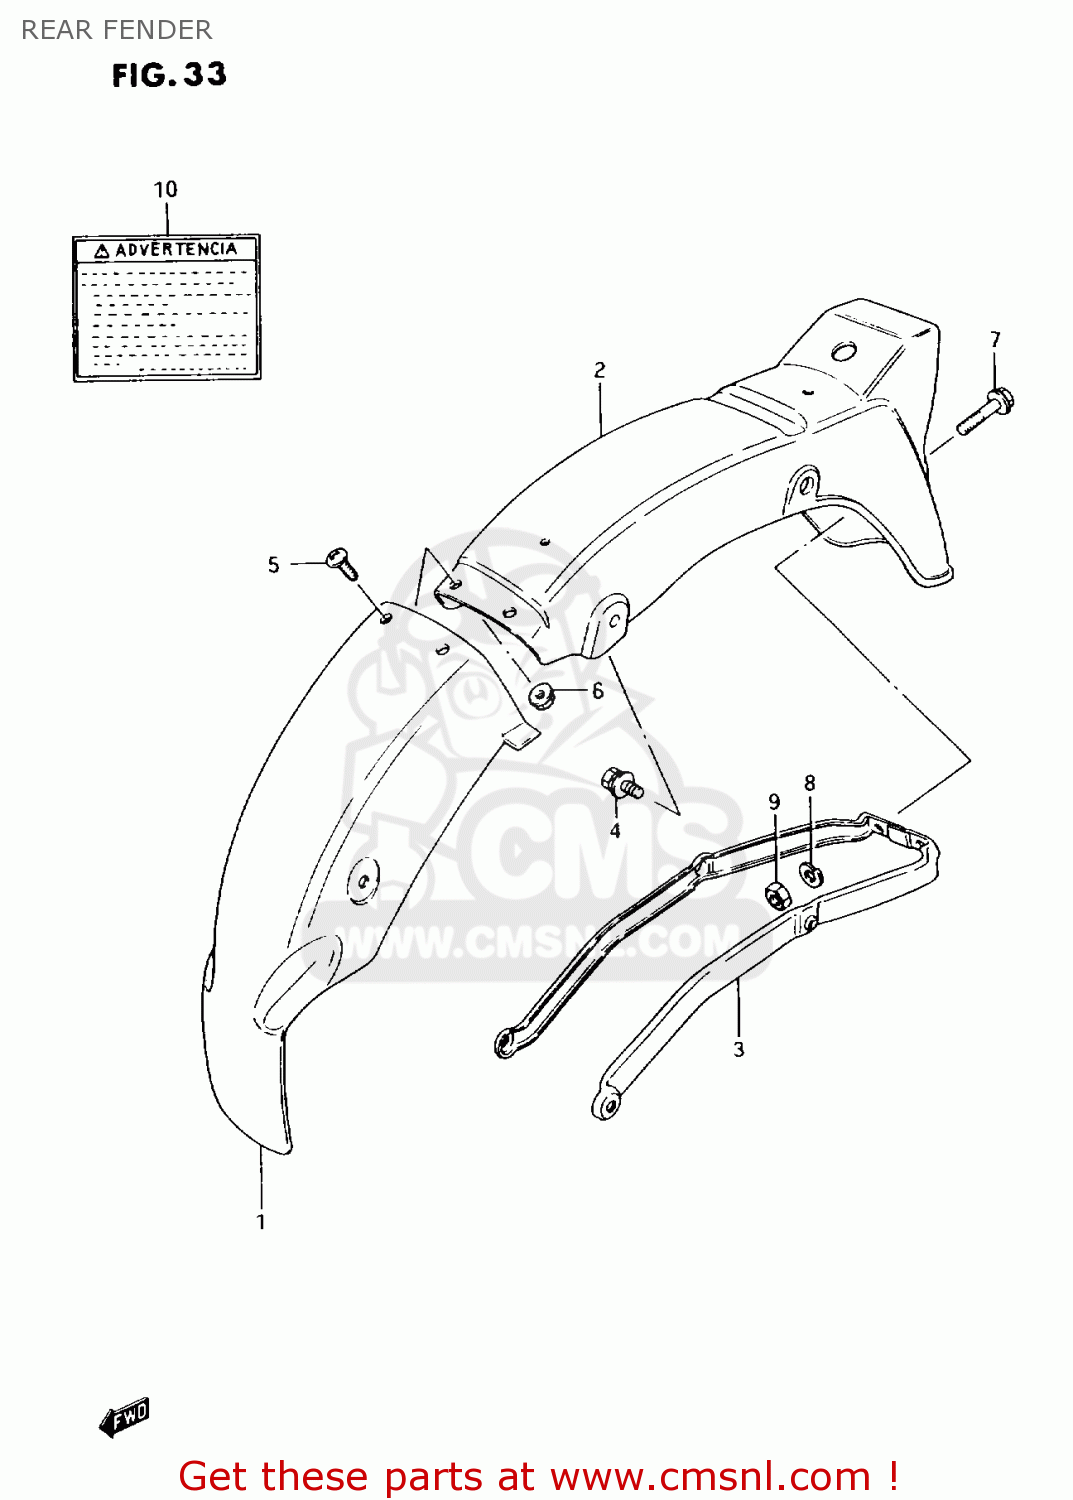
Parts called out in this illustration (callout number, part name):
1	BODY,RR FENDER FR
2	FENDER,RR
3	REINFORCEMENT,RR FENDER
4	BOLT
5	SCREW
6	NUT
7	BOLT
8	LOCK WASHER
9	NUT
10	LABEL,WARNING
11	MANUAL, OWNER'S
